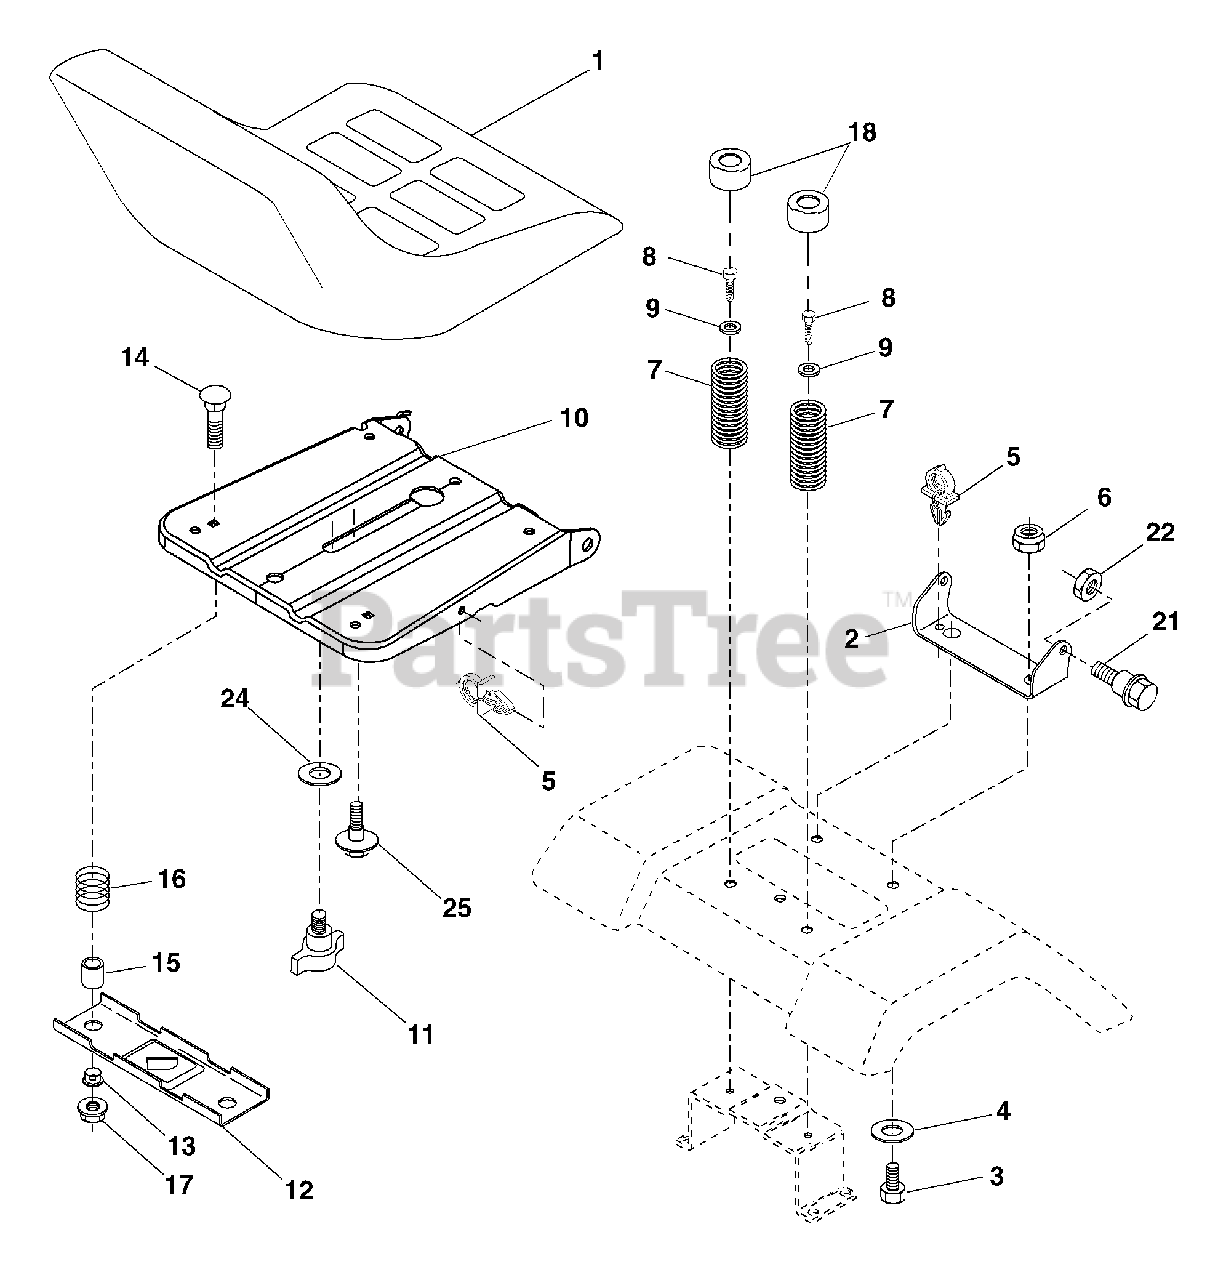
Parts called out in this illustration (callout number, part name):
1	Seat
2	Bracket Pivot Seat
3	Bolt Fin Hex 3/8-16 unc x 1
4	Washer 13/32 x 1 x 10 Ga
5	Clip Push-In
6	Nut Hex w/Ins. 3/8-16 unc
7	Spring Seat Cprsn
8	Screw 3/8-16 x 1-1/2
9	Washer 13/32 x 1 x 14 Ga.
10	Pan Seat
11	Knob Seat Adj. Wingnut
12	Bracket Mounting Switch
13	Bushing Snap Blk Nyl 50 Id
14	Bolt Rdhd Sqnk 1/4-20 x 1-1/2
15	Spacer Split 28x .88 Zinc
16	Spring Cprsn Plate 1.310 Ga
17	Nut Lock 1/4 Lge Flg Gr. 5 Zinc
18	Cap Spring Seat
21	Bolt Shoulder 5/16-18 unc
22	Nut Hex Lock W/Ins 5/16-18
24	Washer 17/32 x 1-3/16 x 12 Ga.
25	Bolt Shoulder 5/16-18 x 62
